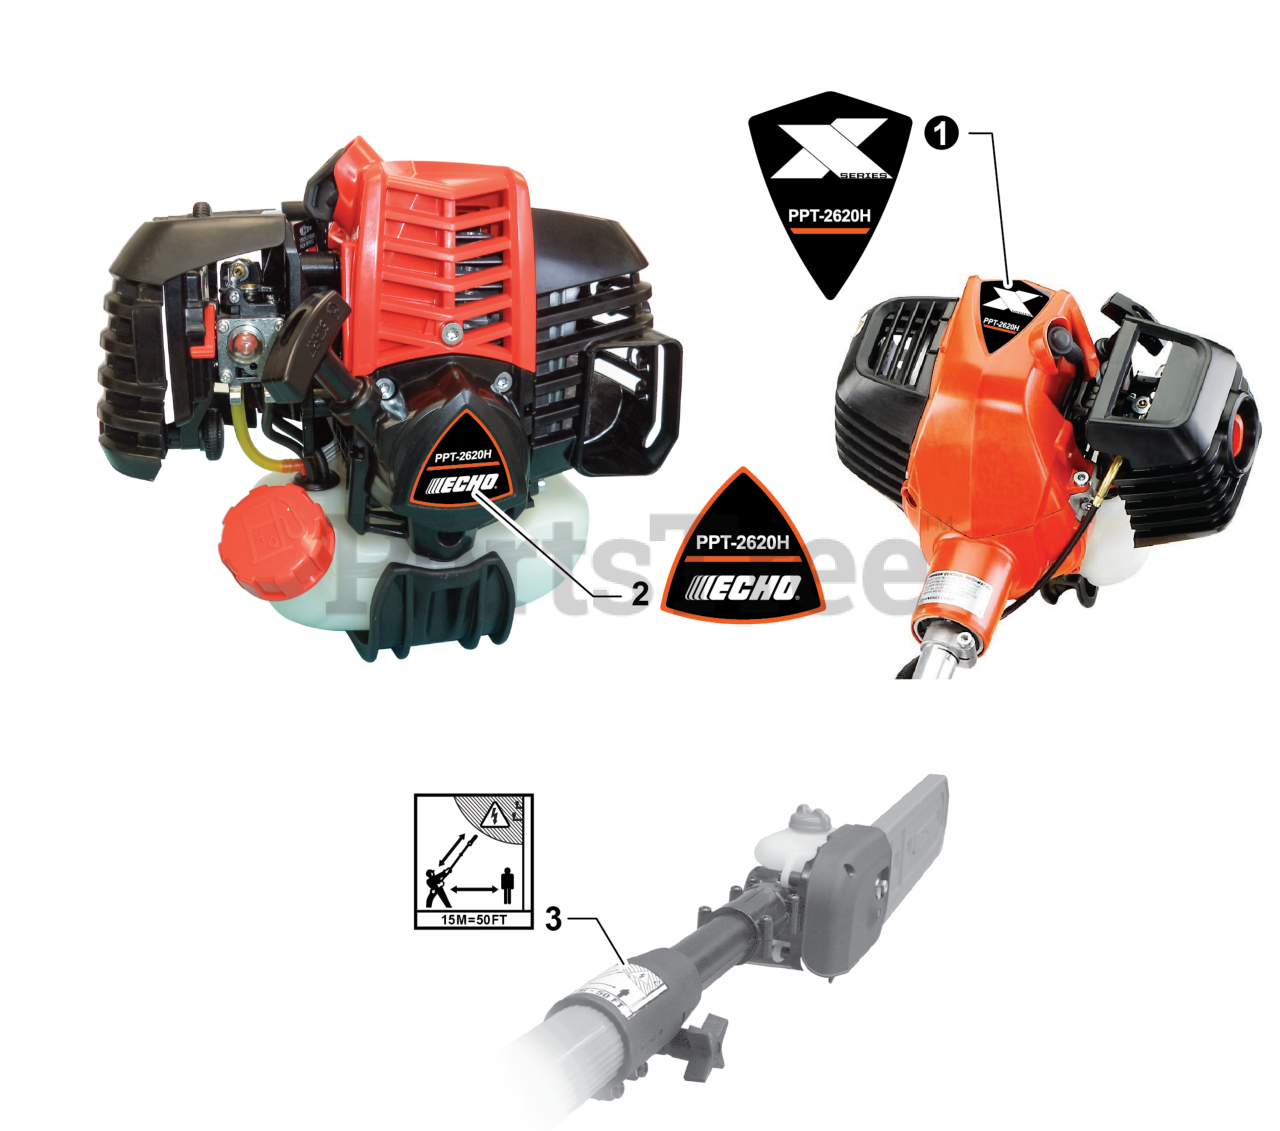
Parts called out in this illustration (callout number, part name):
1	LABEL - MODEL PPT-2620H
2	LABEL - RECOIL STARTER - PPT-2620H
3	LABEL - CAUTION
